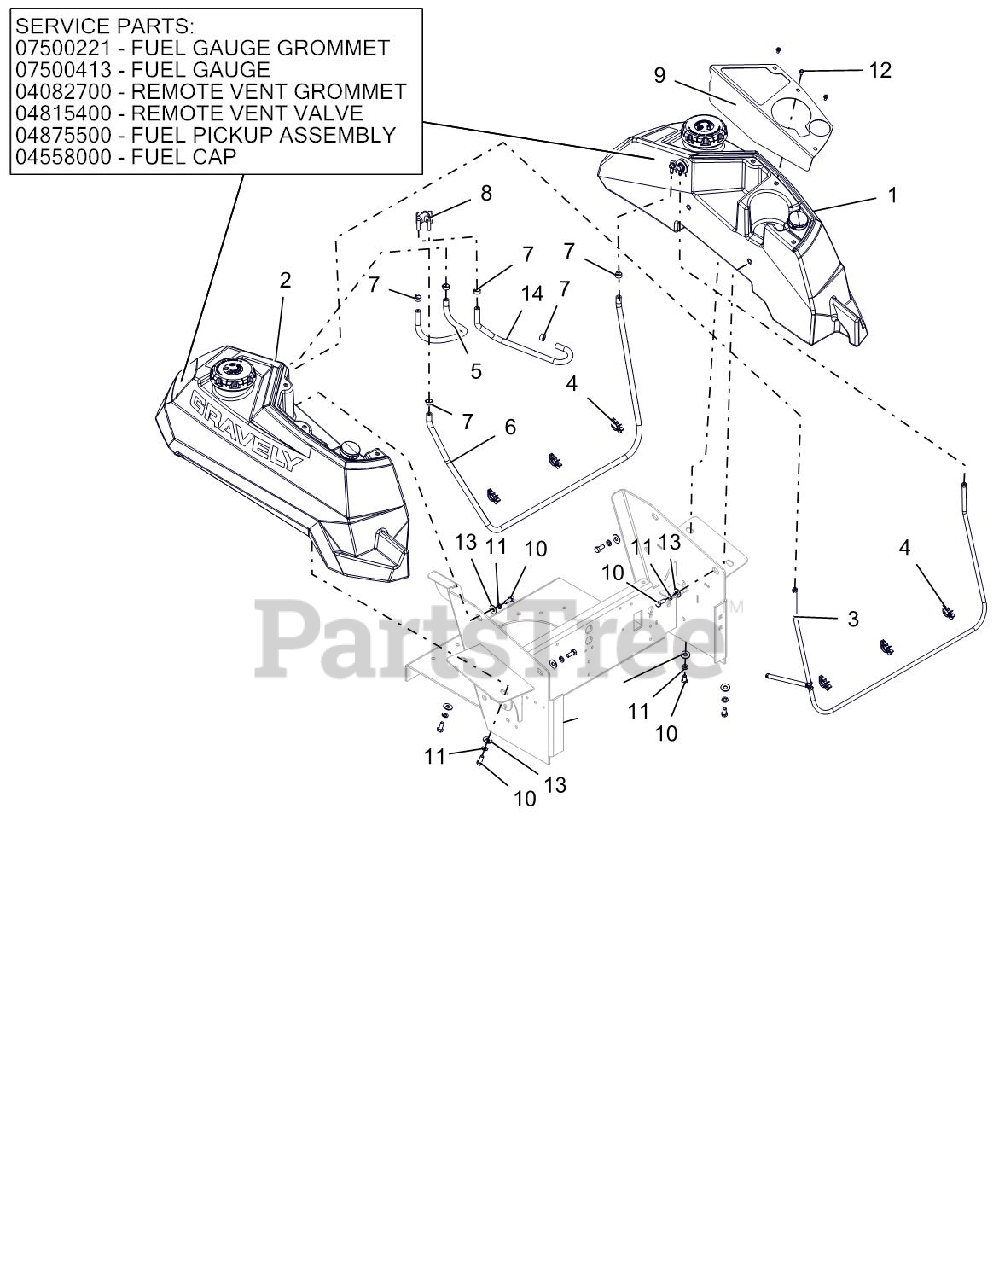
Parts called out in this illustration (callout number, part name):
1	ASM, LH - PT100 FUEL TANK
2	ASM, RH - PT100 FUEL TANK
3	ASM, VAPOR LINE
4	WIRE, CLIP
5	HOSE, .25 LOW PERM FUEL 14.00" LG - RH TANK TO VALVE
6	HOSE, .25 LOW PERM FUEL 48.00" LG - LH TANK TO VALVE
7	CLAMP, FUEL LINE
8	VALVE, FUEL
9	PANEL, PT100 CUPHOLDER (RED)
10	BOLT, HEX 0.313-18X0.75 GR5
11	WSHR-LK .31X.078 REG YWZC
12	SCR-MCH 10-24X.38 HWHSTAINLESS
13	WSHR-FL-STL.38X.875X.083 YWZC
14	.25 LOW-PERM GAS HOSE 16.00" LG - VALVE TO ENGINE
15	FUEL GAUGE GROMMET
16	FUEL GAUGE
17	REMOTE VENT GROMMET
18	REMOTE VENT VALVE
19	FUEL PICKUP ASSEMBLY
20	FUEL CAP
